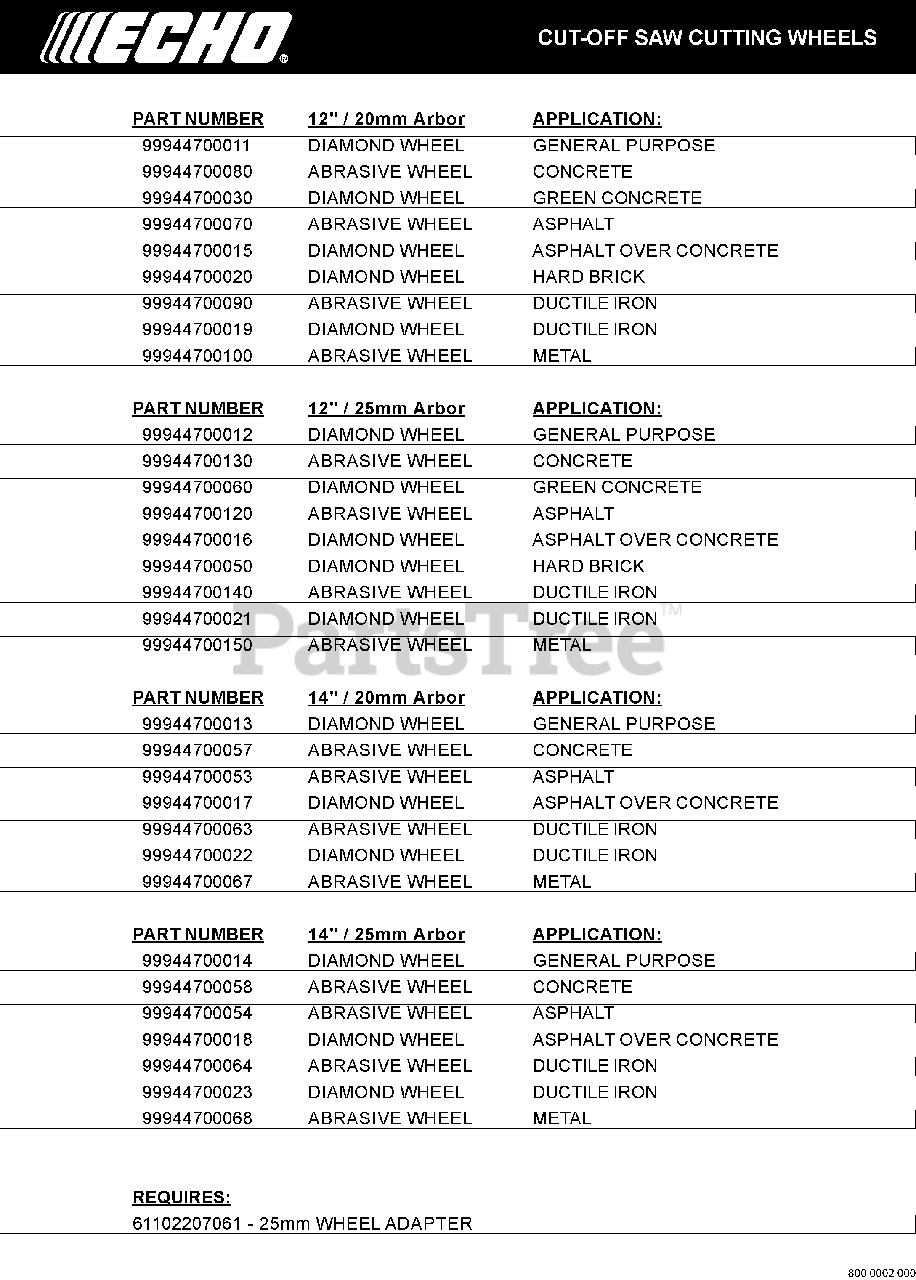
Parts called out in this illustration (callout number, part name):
1	DIAMOND WHEEL
2	ABRASIVE WHEEL 12" - 20mm
3	DRY DIAMOND WHEEL DIA. 12" ARBOR DIA. 20MM
4	ABRASIVE WHEEL 12" - 20mm
5	DIAMOND WHEEL
6	DRY DIAMOND WHEEL DIA. 12" ARBOR DIA. 20MM
7	ABRASIVE WHEEL 12" - 20mm
8	DIAMOND WHEEL
9	ABRASIVE WHEEL 12" - 20mm
10	DIAMOND WHEEL
11	ABRASIVE WHEEL 12" - 25mm
12	DRY DIAMOND WHEEL DIA. 12" ARBOR DIA. 25MM
13	ABRASIVE WHEEL 12" - 25mm
14	DIAMOND WHEEL
15	DRY DIAMOND WHEEL DIA. 12" ARBOR DIA. 25MM
16	ABRASIVE WHEEL 12" - 25mm
17	DIAMOND WHEEL
18	ABRASIVE WHEEL 12" - 25mm
19	DIAMOND WHEEL
20	ABRASIVE WHEEL
21	ABRASIVE WHEEL
22	DIAMOND WHEEL
23	ABRASIVE WHEEL
24	DIAMOND WHEEL
25	ABRASIVE WHEEL
26	DIAMOND WHEEL
27	ABRASIVE WHEEL
28	ABRASIVE WHEEL
29	DIAMOND WHEEL
30	ABRASIVE WHEEL
31	DIAMOND WHEEL
32	ABRASIVE WHEEL
33	WHEEL ADAPTER - 25mm
